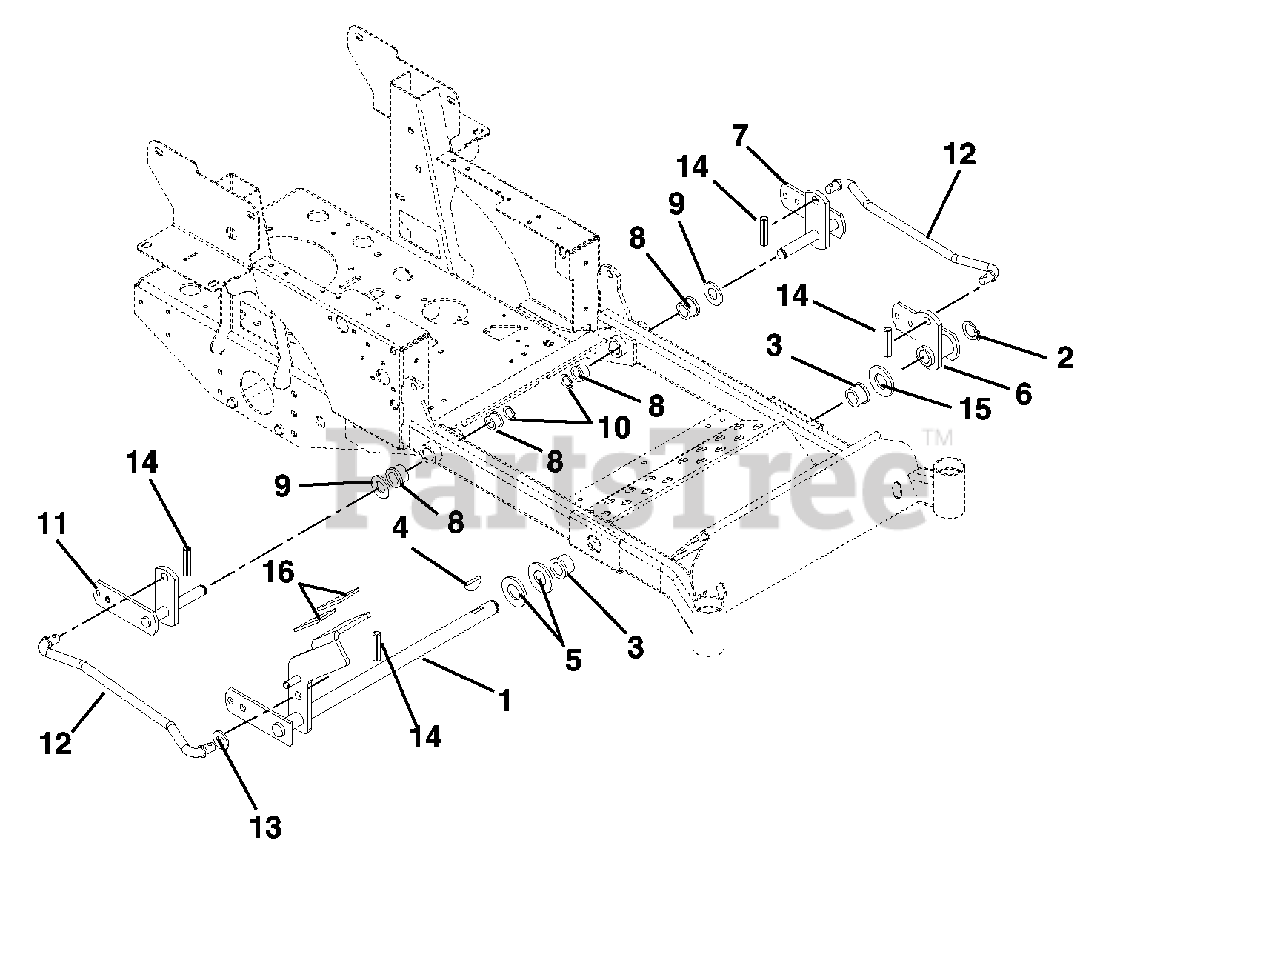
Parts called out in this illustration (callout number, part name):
1	Weldment, Lift Arm
2	Ring, Retaining External 1.00 x .078
3	Bushing, Flange Nylon 1.020 x 1.385 x .75 x 1.75
4	Key, Woodruff .25 x 1.00
5	Washer, Flat-Steel 1.063 x 2.00 x .134
6	Weldment, Lift Arm-Front
7	Weldment, Lift Arm Shaft-Left Hand
8	Bushing, Flange Nylon .762 x 1.0 x .580 x 1.48
9	Washer, Hardened Steel .758 x 1.23 x .031
10	Ring, Retaining External .689 x .077
11	Weldment, Lift Arm Shaft-Right Hand
12	Rod, Lift Assist
13	Washer, Flat Steel .656 x 1.31 x .095
14	Pin, Roll .25 x 1.25
15	Washer, Hardened Thrust 1.00 x 1.55 x .03
16	Grip, Pedal
